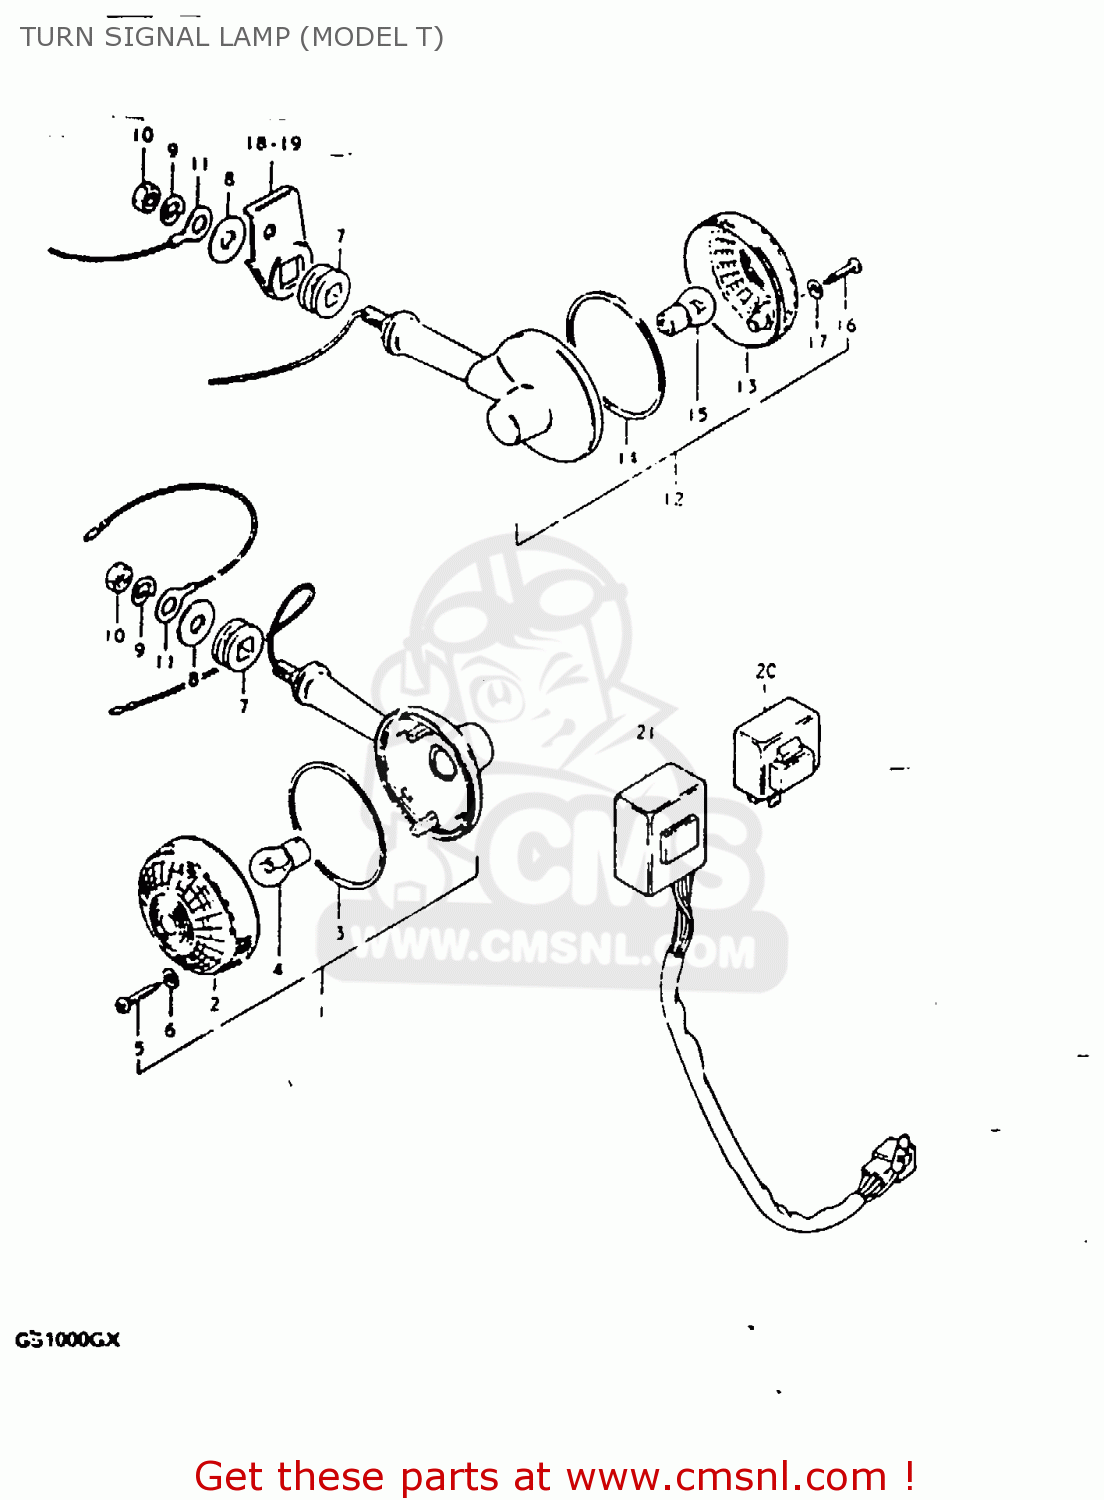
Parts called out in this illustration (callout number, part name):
1	LAMP ASSEMBLY,FRONT TURN SIGNAL
2	LENS
3	GASKET (NAS)
4	BULB(12V23W,STANLEY,A4577A)
5	BOLT
6	GASKET (NAS)
7	CUSHION
8	WASHER
9	LOCK WASHER
10	NUT
11	LEAD WIRE,EARTH
12	LAMP ASSEMBLY,FRONT TURN SIGNAL
13	LENS
14	GASKET (NAS)
15	BULB(12V23W,STANLEY,A4577A)
16	BOLT
17	GASKET (NAS)
18	BRACKET,RR TURNSIGNAL LAMP,R
19	BRACKET,RR TURNSIGNAL LAMP,L
20	RELAY ASSY,TURNSIGNAL
21	UNIT,TURN SIGNAL CONTROL
